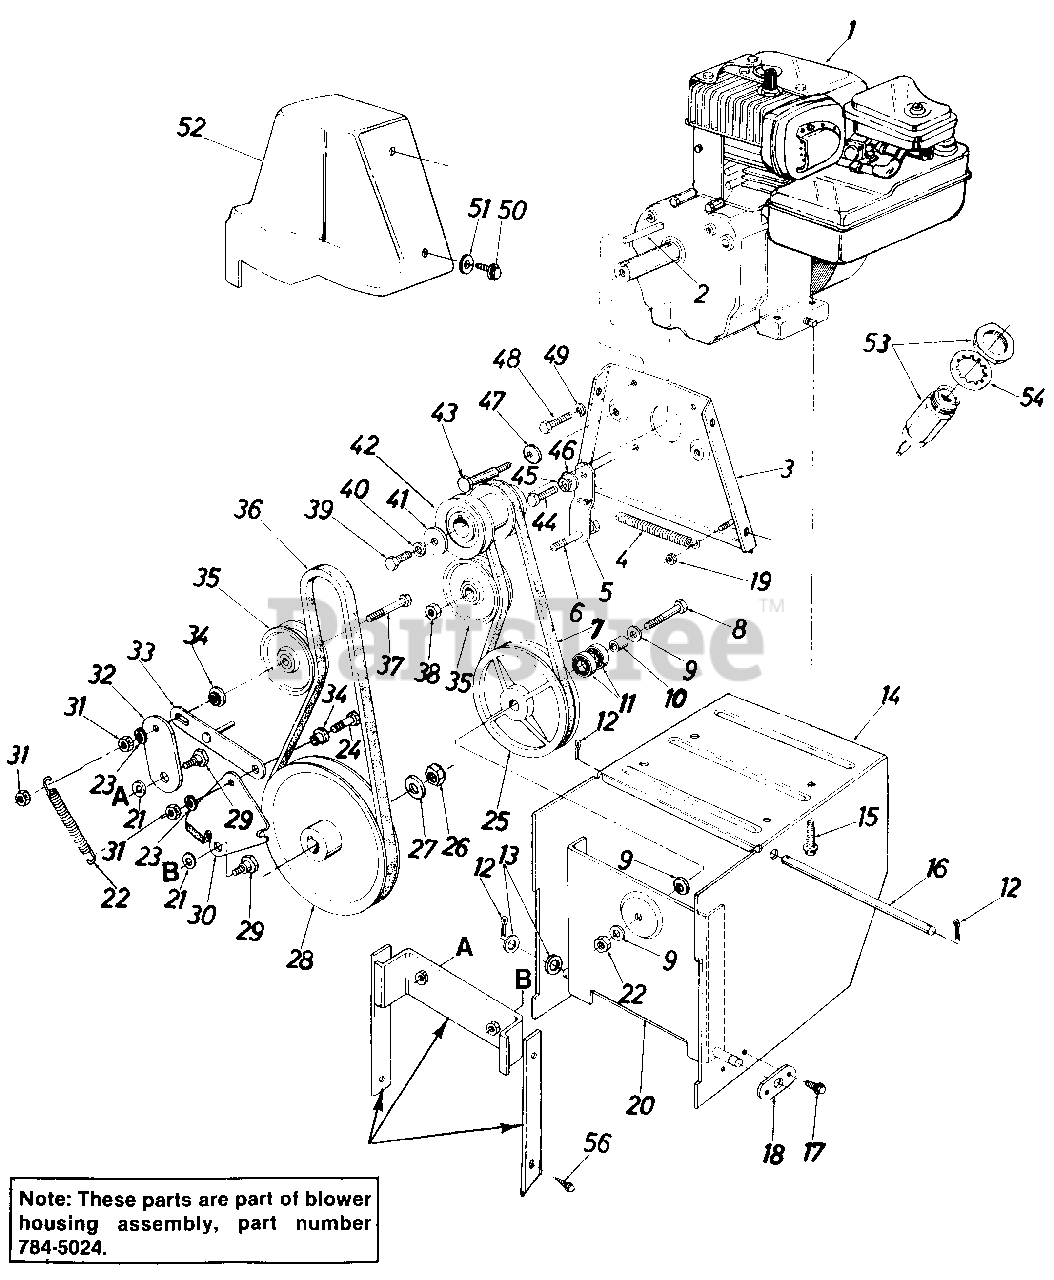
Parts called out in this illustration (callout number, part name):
1	Engine
2	Sq. Key 3/16" x 1.50" Lg.
3	Engine Plate Ass'y.
4	Extension Spring .50" O.D. x 3.91" Lg.
5	Drive Clutch Idler Brkt.
6	Hex Bolt 3/8-24 x 1.25" Lg.
7	"V"-Belt 3/8" x 29.0" Lg.
8	Hex Bolt 3/8-24 x 1.50" Lg.
9	Bell-Wash. .40" I.D. x .88" O.D. x .06
10	Spacer .38" I.D. x 62" O.D. x .75" Lg.
11	Ball Brg. .62" I.D. x 1.38" O.D. x .44
12	Cotter Pin 3/32" Dia. x .75" Lg
13	Fl-Wash. .53" I.D. x 1.00" O.D. x .125
14	Frame Ass'y.
15	Hex Wash. Hd. Self-Tap Scr. 3/8-16 x 1.25" Lg.
16	Shaft .50" Dia. x 9.50" Lg.
17	Hex Wash. Hd. Self-Tap Scr. 1/4-20 x .50" Lg.
18	Axle Bracket
19	Hex L-Nut 1/4-20 Thd.
20	Drive Pulley Support Brkt. Ass'y.
21	Bell-Wash. .40" I.D. x 1.13" O.D.
22	Extension Spring .50" O.D. x 3.97" Lg.
23	L-Wash. 3/8" I.D.
24	Hex Scr. 3/8-16 x 1.25" Lg.
25	6.00" O.D. Drive Pulley Ass'y.
26	Hex Jam Cent. L-Nut 5/8-18 Thd.
27	Fl-Wash. .64" I.D. x .94" O.D. x .06
28	1/2" V-Pulley .625" I.D. x 7.50" O.D.
29	Shld. Bolt .625" Dia. x .170" Lg. (3/8-16)
30	Brake Bracket Ass'y.
31	Hex Ins. L-Nut 3/8-16 Thd.
32	Auger Clutch Idler Brkt.
33	Brake Linkage Ass'y.
34	Shld. Spacer .625" I.D.
35	Flat Idler 2.25" G.D.
36	"V"-Belt 3/8" x 38" Lg.
37	Hex Bolt 3/8-16 x 2.25" Lg.
38	Hex Ins. Jam L-Nut 3/8-24 Thd.
39	Hex Bolt 3/8-24 x 1.50" Lg.
40	L-Wash 3/8" I.D.
41	Fl-Wash .40" I.D. x 1.25" O.D.
42	Double Groove Engine Pulley
43	Shld. Scr. .498" x 3.0" Lg.
44	Hex Bolt 5/16-24 x 1.00" Lg.
45	L-Wash 5/16" I.D.
46	Shld. Spacer .320" I.D.
47	Bell-Wash. .40" I.D. x .88" x .06
48	Hex Bolt 5/16-24 x .62" Lg.
49	L-Wash. 5/16" I.D.
50	Hex Wash. Hd. Self-Tap Scr. 1/4-20 x .50" Lg.
51	Fl-Wash. .28" I.D. x .75" O.D. x .06
52	Belt Cover
53	Ignition Switch
54	Int. L-Wash. 5/8" I.D.
56	Hex Wash. Hd. Self-Tap Scr. 3/8-16 x .75" Lg.
